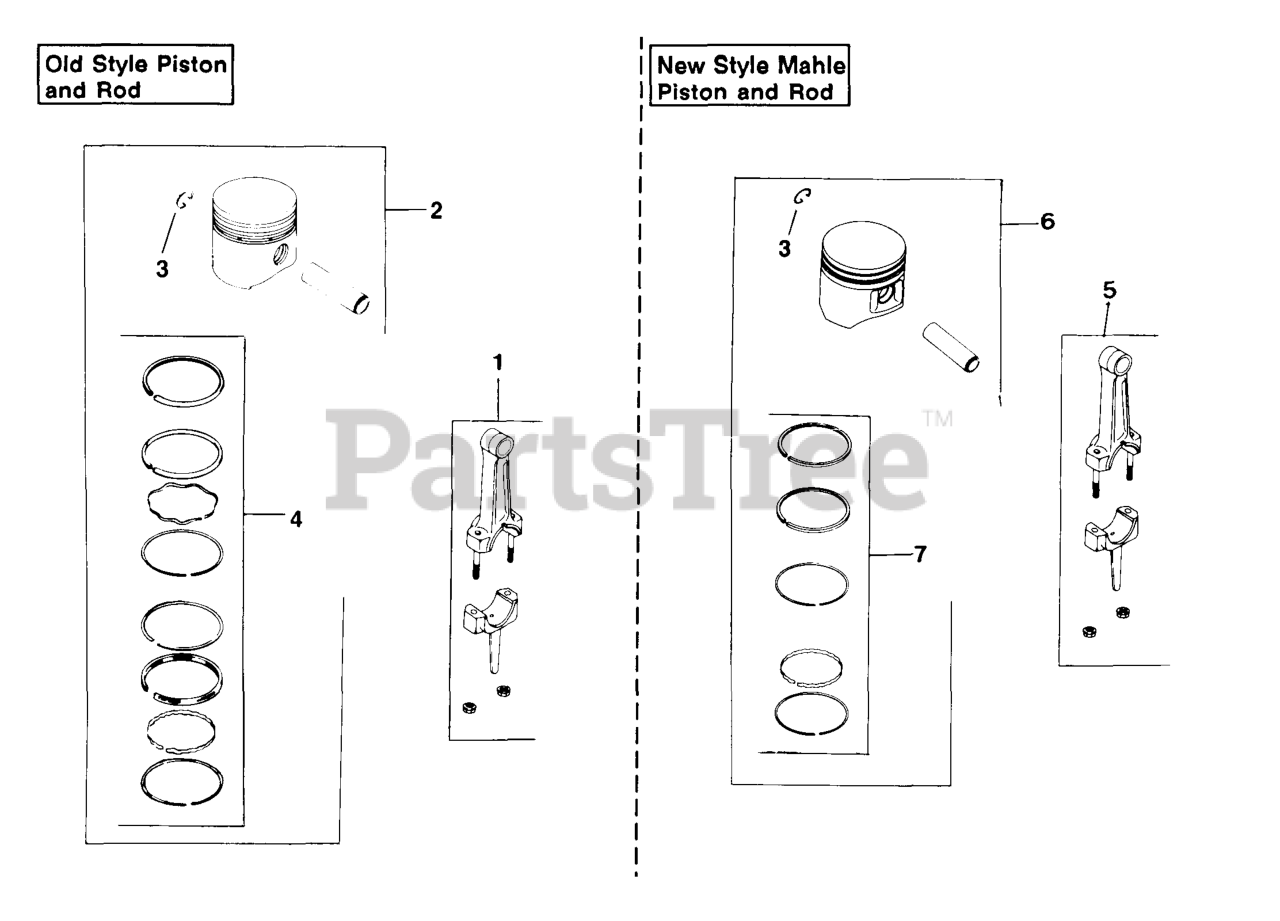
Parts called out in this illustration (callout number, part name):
1	ROD .010 - DISCONTINUED
2	KIT, PISTON W/RING SET STD - DISCONTINUED
2	KIT, PISTON W/RING SET .003
2	PISTON W/RING SET .010
2	PISTON W/RING SET .020 - DISCONTINUED
2	KIT, PISTON W/RING SET .030 - DISCONTINUED
3	RETAINER
4	RINGS STD.
4	RINGS .010
4	RINGS .020
4	RINGS .030
5	ROD, STD
5	ROD .010
6	PISTON W/RING SET STD - DISCONTINUED
6	PISTON W/RING SET .003 - (#DSC)
6	PISTON W/RING SET .010 - DISCONTINUED
6	KIT, PISTON W/RING SET .020 - DISCONTINUED
6	PISTON W/RING SET .030 - DISCONTINUED
7	RINGS STD-DISCONTINUED
7	RINGS .010 - DISCONTINUED
7	RINGS .020
7	RINGS .030 - DISCONTINUED
4706709-S	ROD STD. - DISCONTINUED
